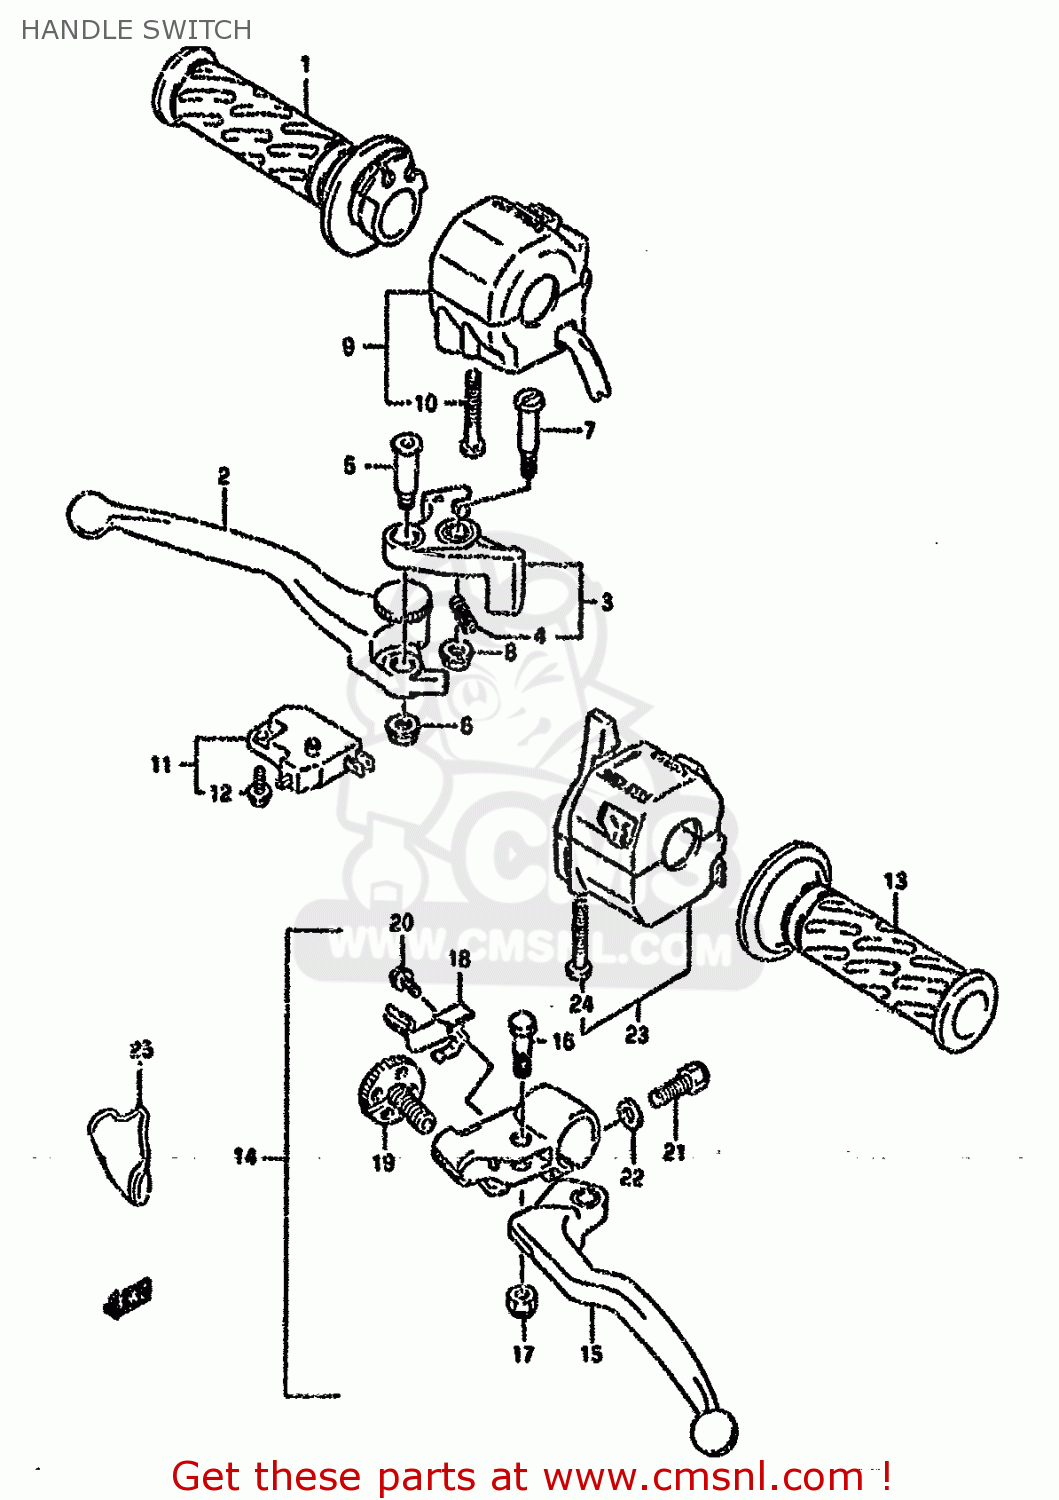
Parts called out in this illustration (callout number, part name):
1	GRIP,THROTTLE
2	LEVER,ADJUST
3	KNOCKER
4	SPRING
5	BOLT,LEVER
6	NUT
7	BOLT,LEVER PIVOT
8	NUT 6MM
9	SWITCH,HANDLE,
10	SCREW, 5X45
11	SWITCH ASSEMBLY,STOP
12	SCREW
13	GRIP,LEFT
14	LEVER ASSY,CLUTCH
15	LEVER,CLUTCH
16	BOLT,LEVER PIVOT
17	NUT
18	ADJUST,SPRING
19	ADJUSTER,LOCK
20	SCREW
21	BOLT
22	WASHER
23	SWITCH,HANDLE,
24	SCREW, 5X45
25	COVER,CLUTCH LEVER
